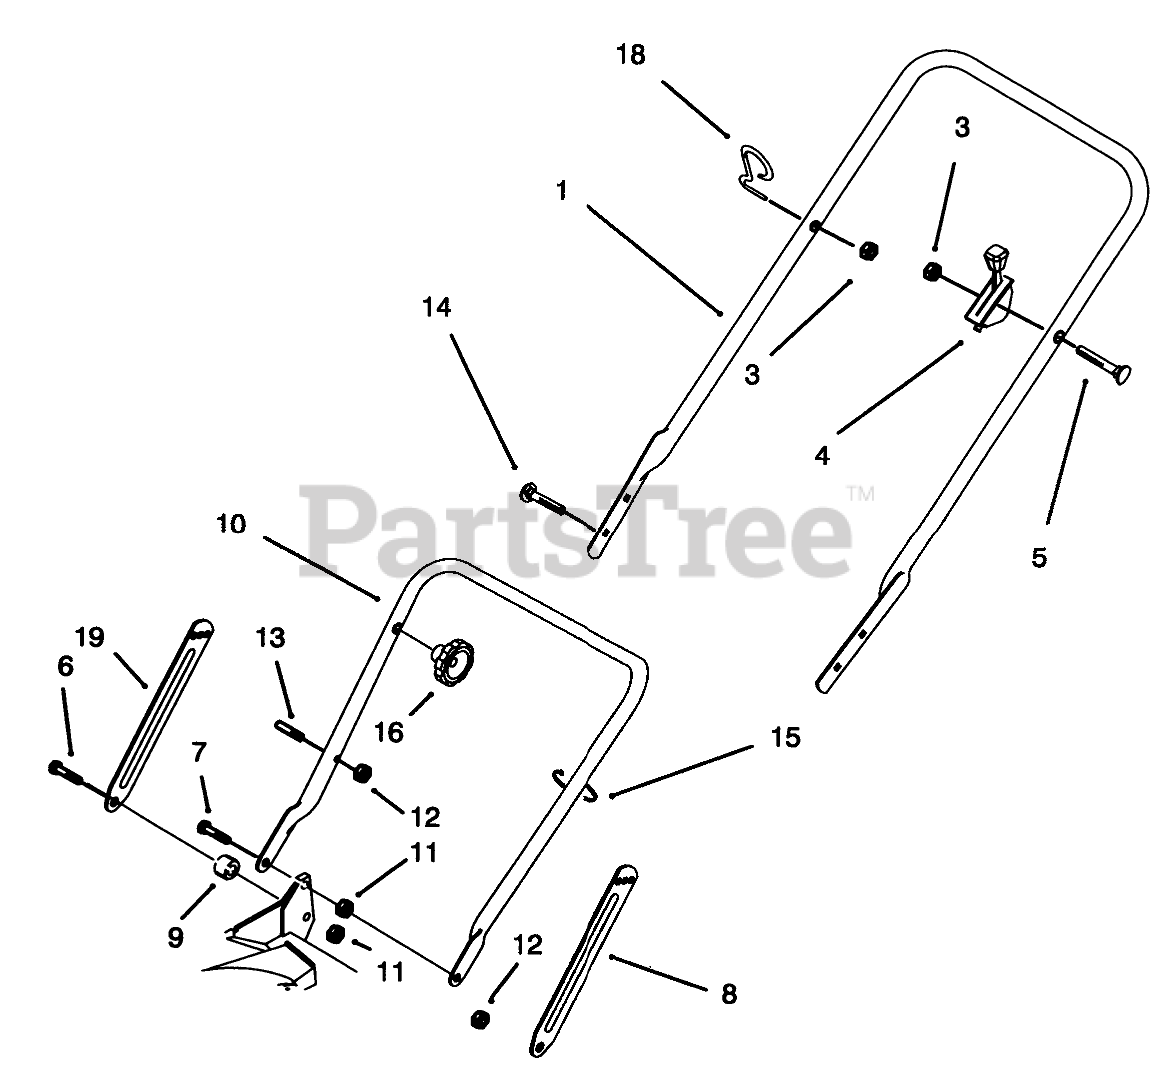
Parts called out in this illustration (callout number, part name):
1	Handle-Upper
3	NUT-LOCK, NI
4	THROTTLE CONTROL
5	SCREW-HANDLE
6	SCREW-SHOULDER
7	SCREW-SHOULDER
8	Latch-Handle
9	SPACER
10	LOWER HANDLE ASM
11	NUT-LOCK, NI
12	NUT-LOCK, NI
13	HANDLE PIN
14	SCREW-HANDLE
15	TIE-CABLE
18	GUIDE-ROPE
19	Latch-Handle
